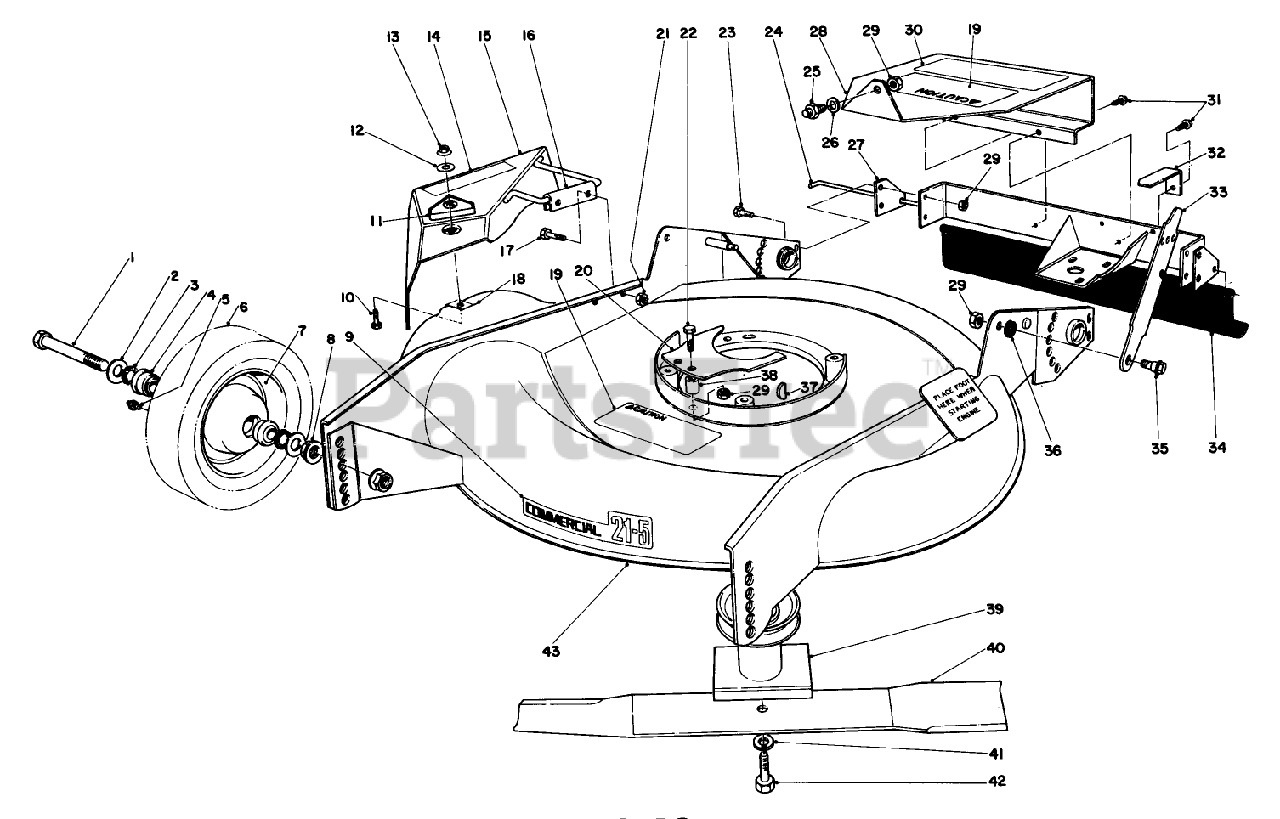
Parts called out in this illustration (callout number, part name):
1	SCREW-HH
2	WASHER-FLAT
4	BEARING-BALL
5	FITTING-GREASE
8	NUT-HF
10	SCREW-HH
11	DECAL-DANGER
12	WASHER-FLAT
13	NUT-LOCK, HHF
14	Decal-Deflector Cover Caution
17	SCREW-HH
18	NUT-SPEED
19	Decal-Safety Instruction
20	Belt Guide-Front
22	SCREW-HH
23	SCREW-HH
24	SAFETY SHIELD ROD
25	BRIGGS #93583
26	Washer
35	SCREW-SHOULDER
36	SPACER
37	KEY-WOODRUFF
38	Spacer
39	Blade Retainer
40	BLADE
41	WASHER-LOCK
43	Housing
